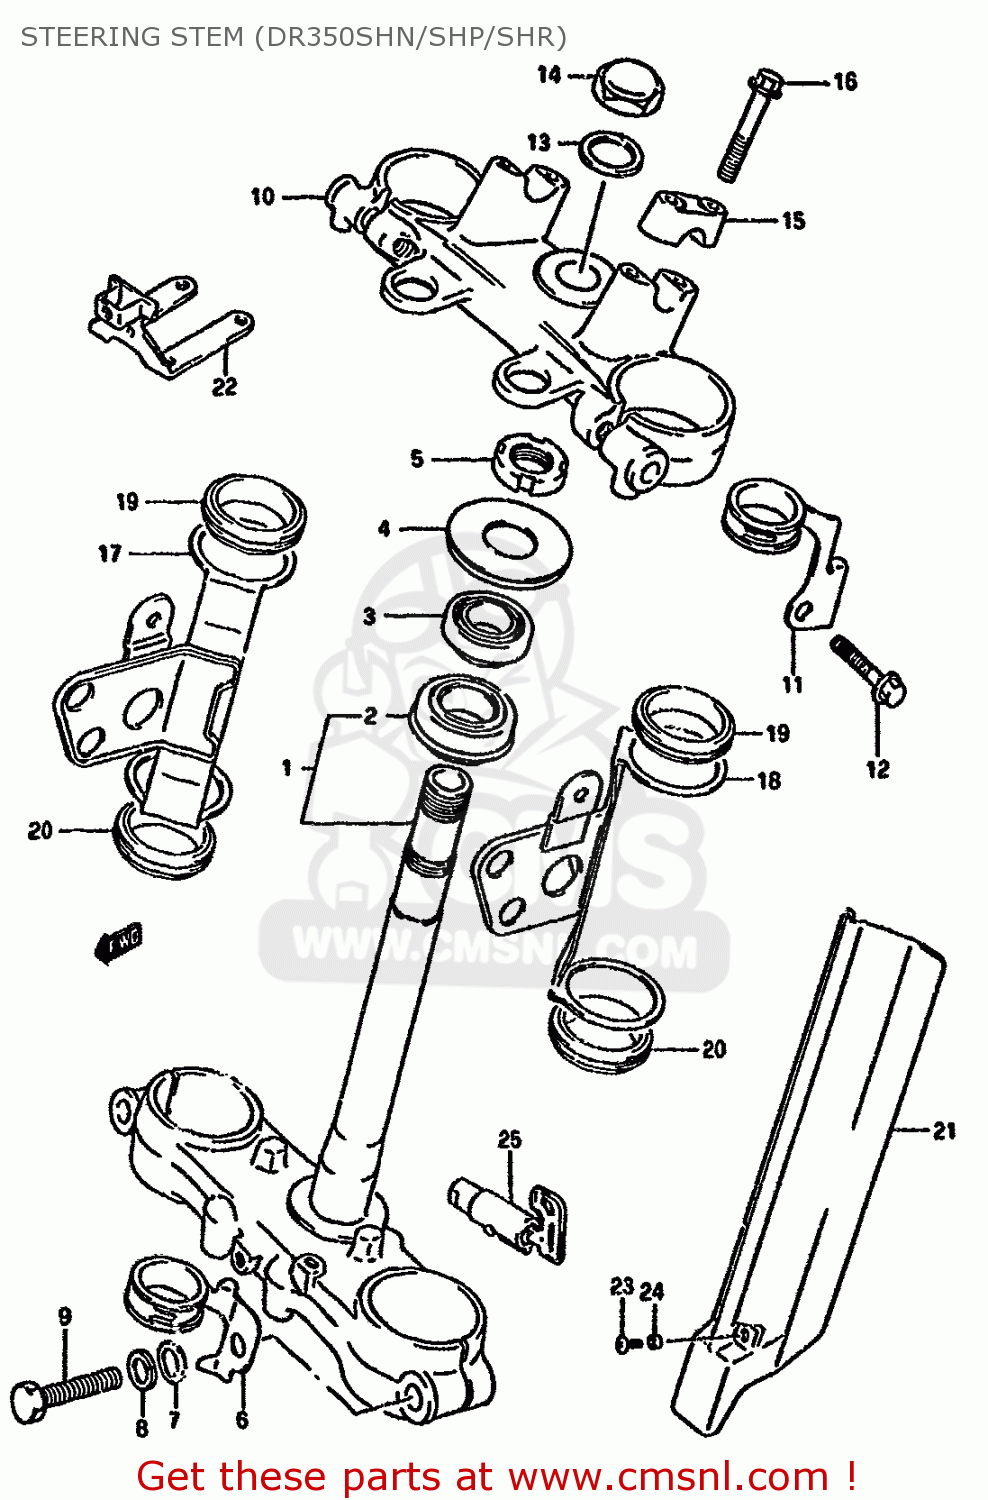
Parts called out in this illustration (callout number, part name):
1	STEM,STEERING
2	BEARING(30X55X17)
3	TAPER,ROLLER BEARING
4	SEAL,STEERING UPR DUST
5	NUT,STEERING STEM
6	GUIDE,CABLE LWR,L
7	WASHER
8	LOCK WASHER
9	BOLT,STEERING STEM
10	HEAD,STEERING STEM
11	GUIDE,CABLE UPR,L
12	BOLT
13	NUT
14	NUT,CAP
15	HOLDER,HANDLE UPR
16	BOLT
17	BRACKET,HEADLAMP RH
18	BRACKET,HEADLAMP LH
19	DAMPER,HEADLAMP HSG BRKT UPR
20	DAMPER,HEADLAMP HSG LWR
21	PROTECTOR,FR FORK,R
22	BRACKET,HEADLAMP COVER
23	SCREW
24	SPACER (5.5X8X4)
25	LOCK ASSY,STEERING(NEIMAN)
